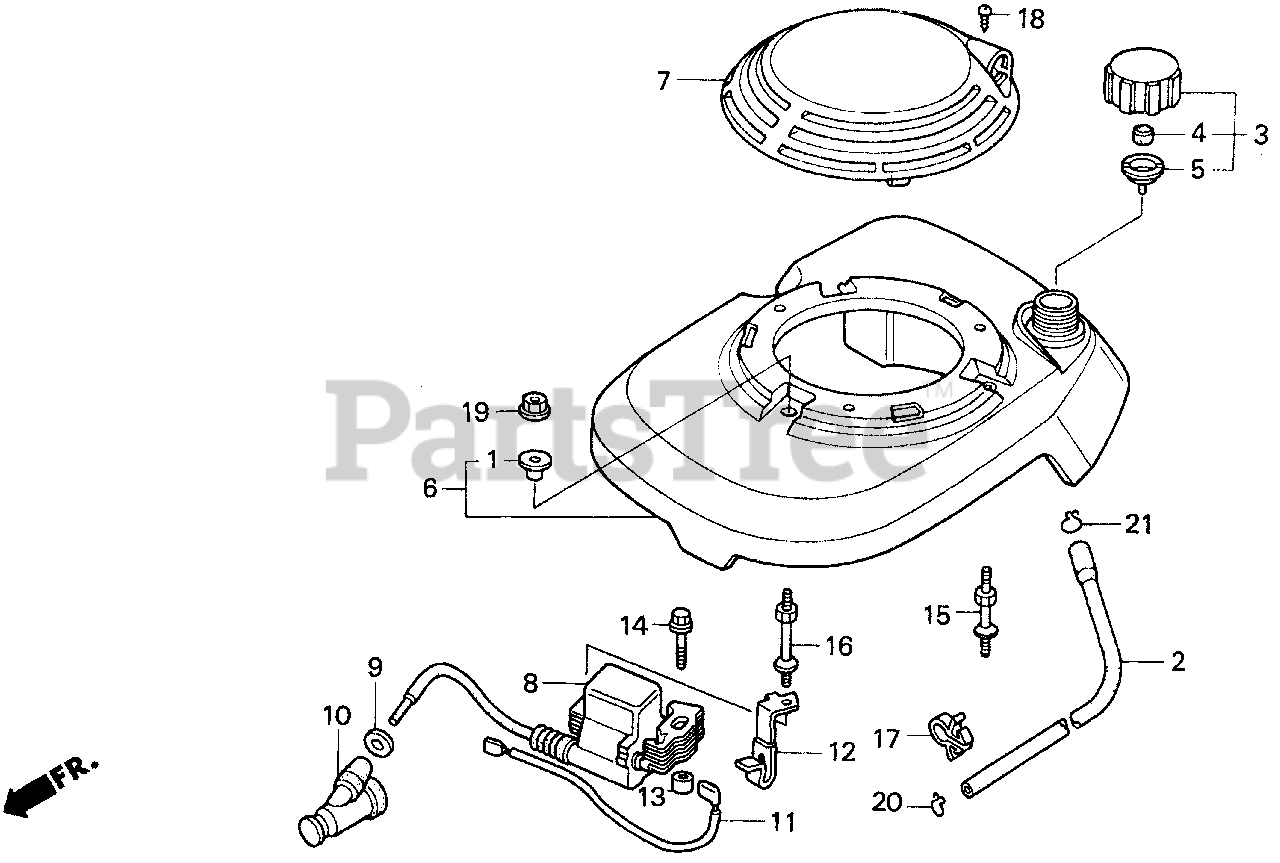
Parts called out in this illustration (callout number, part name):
1	COLLAR, AIR CLEANER
2	TUBE, FUEL TANK
2	TUBE, FUEL TANK (135MM)
2	BULK HOSE, FUEL (5.5X3000) (5.3X135)
3	CAP ASSY., FUEL TANK
4	SPONGE, FUEL CAP BREATHER
5	GASKET, FUEL CAP
6	COVER, FAN
7	HOOD, FAN COVER *R8* (SMOOTH) (BRIGHT RED)
7	HOOD, FAN COVER (GLOSSY FINISH)
8	COIL ASSY., IGNITION
9	GROMMET, IGNITION WIRE
10	CAP ASSY., NOISE SUPPRESSOR
14	BOLT, FLANGE (6X25) (CT200)
15	BOLT A, STUD
16	BOLT B, STUD
17	CLIP B, CABLE
18	SCREW, TAPPING (4X20)
19	NUT, FLANGE (6MM)
20	CLIP, TUBE (B8)
21	CLIP, TUBE (B10)
